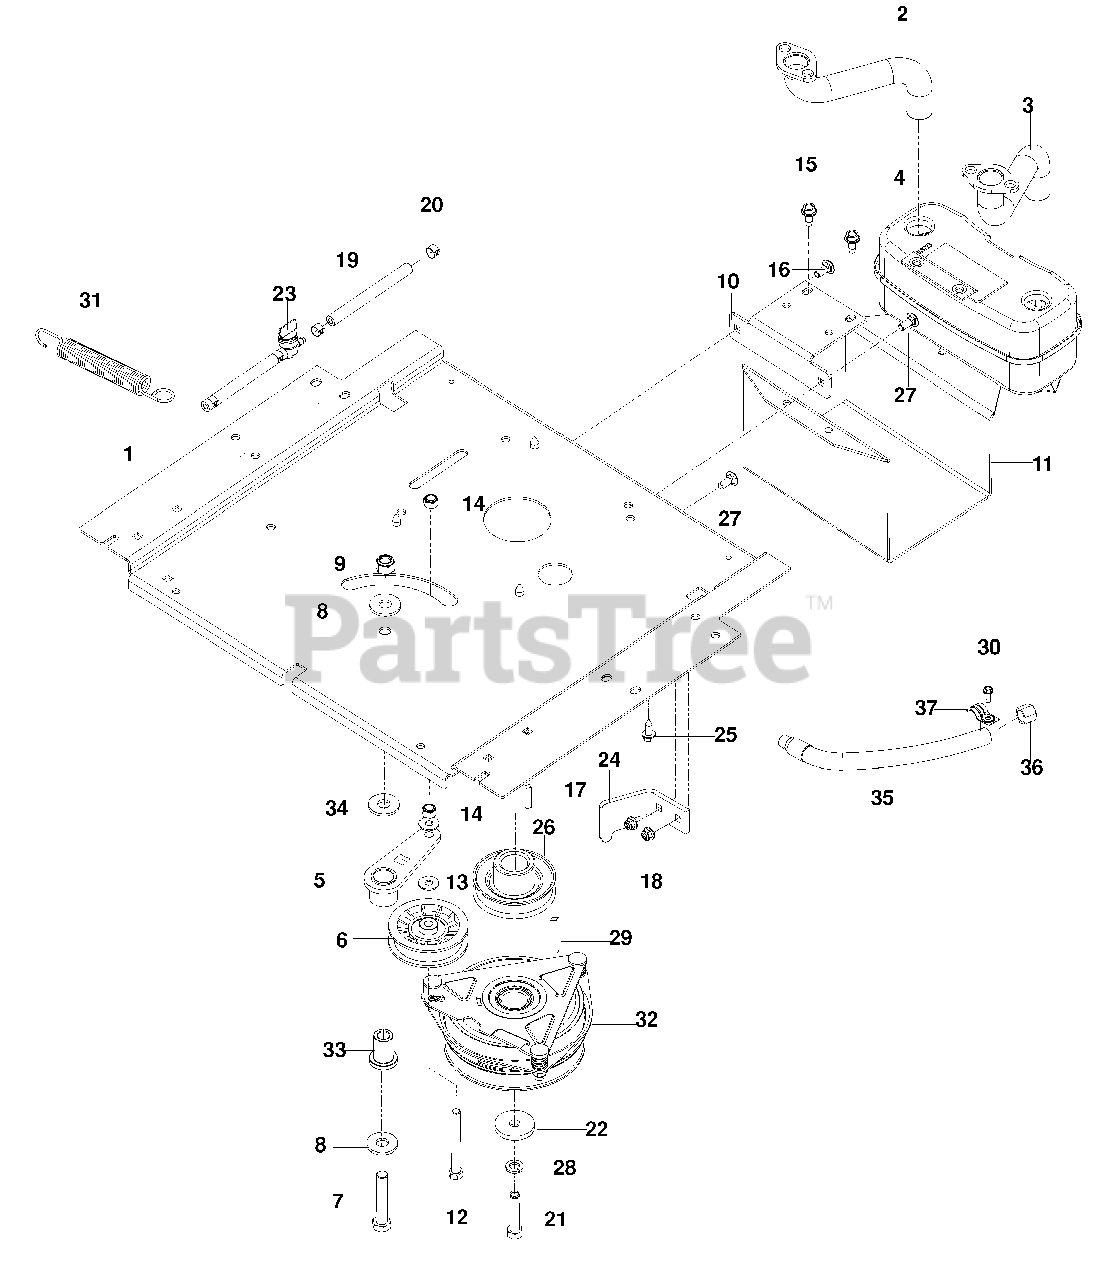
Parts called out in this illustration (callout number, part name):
1	PLATE, ENGINE
2	EXHAUST TUBE, RT
3	EXHAUST TUBE, LT
4	MUFFLER ASM TWIN
5	ARM, IDLER
6	PULLEY, IDLER
7	HCS 1/2-13 x 2 3/4
8	WASHER 1/2 FLT
9	NUT 1/2-13 HEX NYLOC
10	BRACKET, MUFFLER
11	GUARD, MUFFLER
12	HCS 3/8-16 x 3 1/2 TPBLT
13	WASHER 5/16 STD FLT
14	NUT 3/8-16 HEX NYLOC
15	BOLT 5/16-18 x 3/4 THD FRM
16	RHSNB 5/16-18 x 3/4
17	KEY 1/4 SQ x 1 1/4
18	NUT 5/16-18 FLANGE NYLOC
19	FUEL LINE 5"
20	CLAMP, HOSE
21	HCS 7/16-20 x 2 GR8
22	WASHER, HEAVY
23	VALVE, FUEL
24	STOP, CLUTCH
25	HHFS 3/8-16 x 1 THD FRM
26	PULLEY, DRIVE
27	RHSNB 5/16-18 x 1
28	WASHER 5/16 SLW
29	KEY 1/4 SQ x 2
30	SCREW 1/4-20 x 5/8 SLF TAP
31	SPRING, DECK DRIVE
32	CLUTCH, 150 FT/LBS
33	PIVOT, IDLER
34	WASHER, HEAVY
35	HOSE, DRAIN
